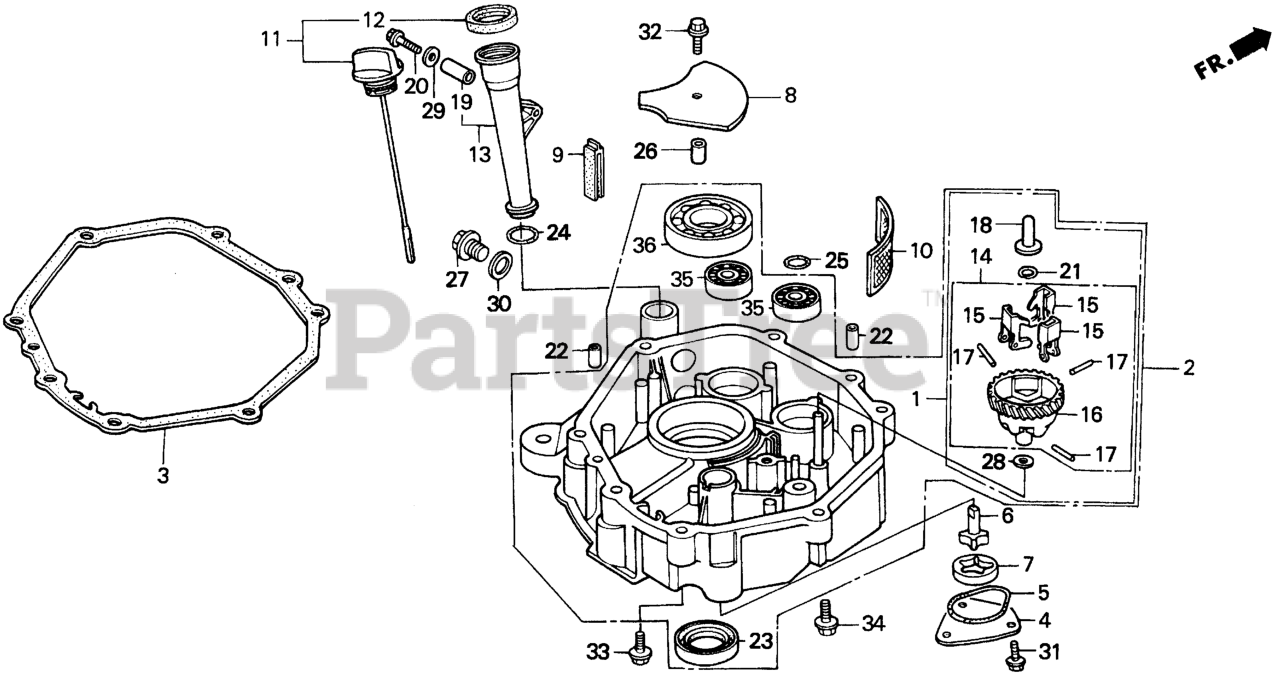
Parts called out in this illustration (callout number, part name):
1	GOVERNOR KIT Use from Engine SN 2086153.
1	GOVERNOR KIT Use up to Engine SN 2086152.
2	PAN ASSY., OIL (NOT AVAILABLE)
2	PAN ASSY., OIL
3	GASKET, OIL PAN
4	COVER, OIL PUMP
5	O-RING, PUMP COVER
6	ROTOR (INNER)
7	ROTOR, OIL PUMP (OUTER)
8	PLATE, OIL FILTER
9	RUBBER, OIL RETURN
10	SCREEN, OIL FILTER
11	CAP ASSY., OIL FILLER
12	GASKET, OIL FILLER CAP
13	EXTENSION, OIL FILLER
14	GOVERNOR ASSY.
15	WEIGHT, GOVERNOR
16	HOLDER, GOVERNOR WEIGHT
17	PIN, GOVERNOR WEIGHT
18	SLIDER, GOVERNOR
19	COLLAR, EXTENSION Use up to Engine SN 1257294.
20	BOLT, FLANGE (6X35)
21	CLIP, GOVERNOR HOLDER
22	PIN, DOWEL (8X12)
23	OIL SEAL (35X52X8)
24	O-RING (22.5X2.2) Use from Engine SN 1257295.
25	O-RING (11.8X2.4)
26	COLLAR, OIL FILTER SETTING
27	BOLT, DRAIN PLUG (20MM)
28	WASHER, PLAIN (6MM)
29	WASHER, PLAIN (6MM)
30	WASHER, DRAIN PLUG (20MM)
31	BOLT, FLANGE (6X12) Use up to Engine SN 1543277.
32	BOLT, FLANGE (6X25)
33	BOLT, FLANGE (8X40)
34	BOLT, FLANGE (8X40)
34	BOLT, FLANGE (8X60)
35	BEARING, RADIAL BALL (6202)
36	BEARING, RADIAL BALL (6207)
